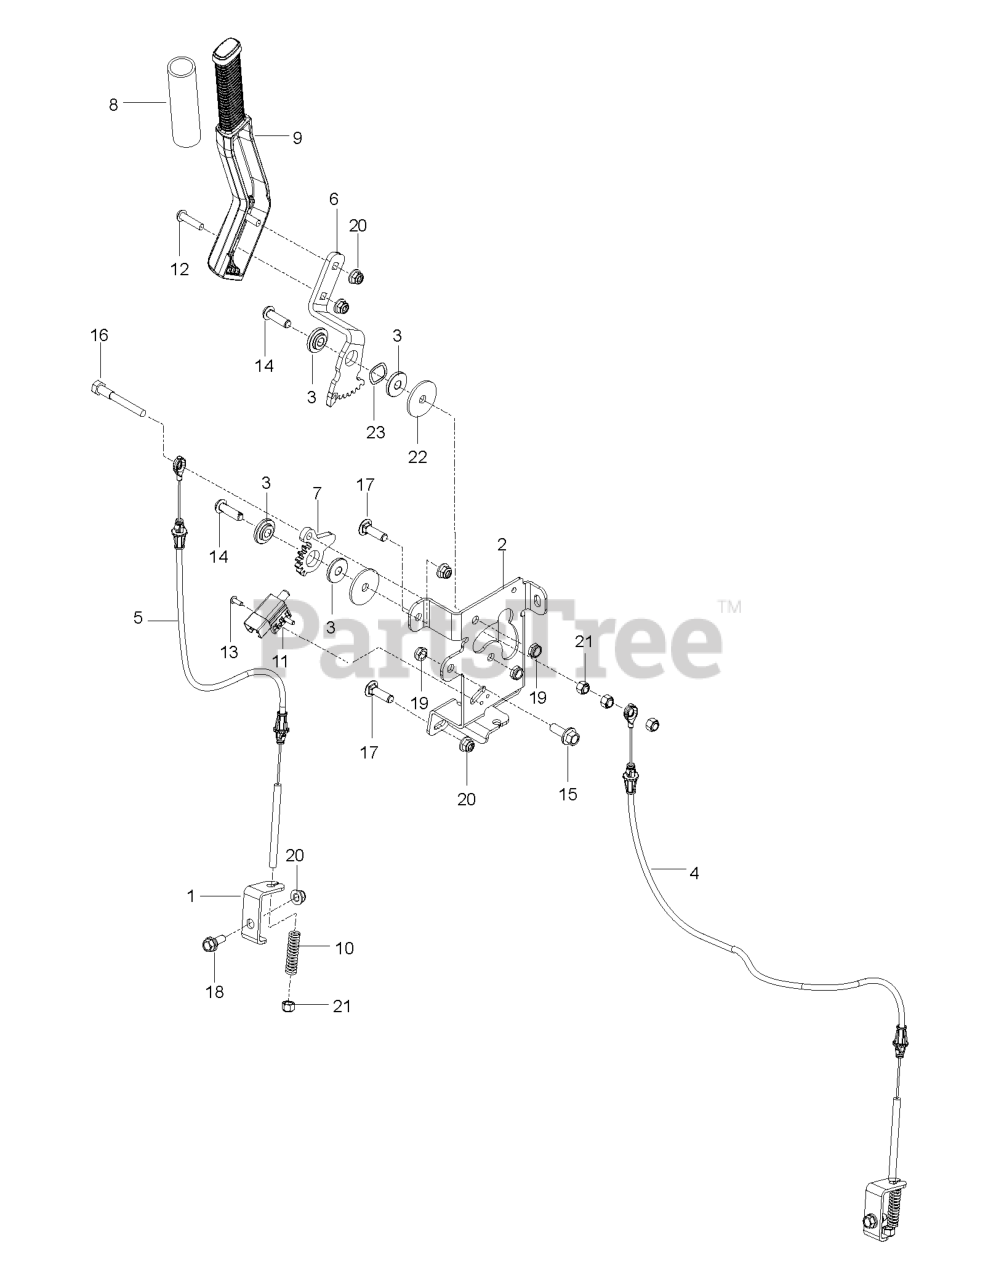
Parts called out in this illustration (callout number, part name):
1	BRACKET BRAKE ARM; PIVOT
2	BRACKET PARKING BRAKE;STAND ON
3	BUSHING, BRAKE
4	CABLE PARKING BRAKE;STAND ON;L
5	CABLE PARKING BRAKE;STAND ON;R
6	GEAR INPUT;PARKING BRAKE;STAND
7	GEAR OUTPUT;PARKING BRAKE;STAN
8	GRIP PARKING BRAKE; STAND ON
9	LEVER PARKING BRAKE; STAND ON
10	SPRING PARKING BRAKE; STAND ON
11	SWITCH INTERLOCKT
12	SCREW.BUTTHEAD.5/16-18X1-1.25
13	SCREW.BUTTONHD.10-24X1/2.(2 2)
14	SCREW HEXALOBULAR SOCKET BUTTO
15	HHFS 3/8-16 X 1 GRD 5 ZD
16	BOLT HEXAGON SHOULDER 5/16-18
17	RHSSNB 5/16C X 1.0
18	BOLT, SHOULDER
19	NUT HEX 3/8-16 NYLON, THIN
20	5/16-18 NYLOC FLANGE NUT
21	NUT 5/16 NYLOC
22	WASHER, 3/8 SPEC
23	WASHER, .825 X 1.087, WAVE
